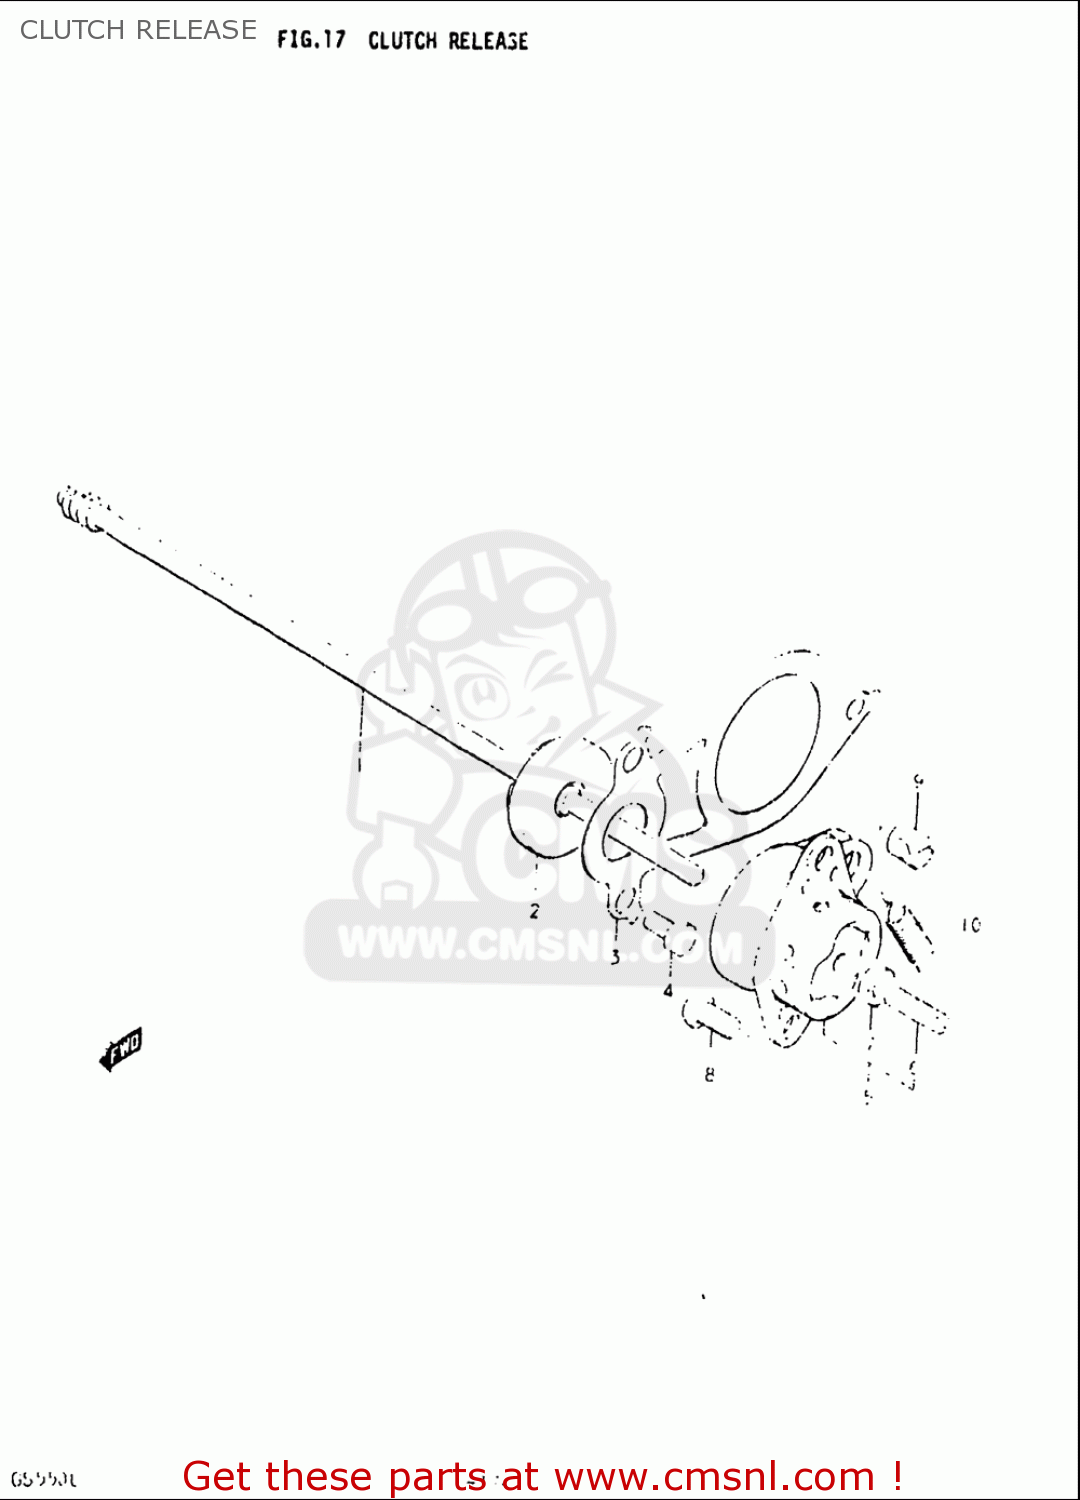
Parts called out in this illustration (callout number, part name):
2	SEAL,OIL(6X34X10)
3	RETAINER,CL PUSH ROD OIL SEAL
4	BOLT
5	SCREW ASSY,CLUTCH RELEASE
6	SCREW(6X25)
7	NUT
8	SCREW
9	PIECE,RELEASE ARM END
10	SPRING
